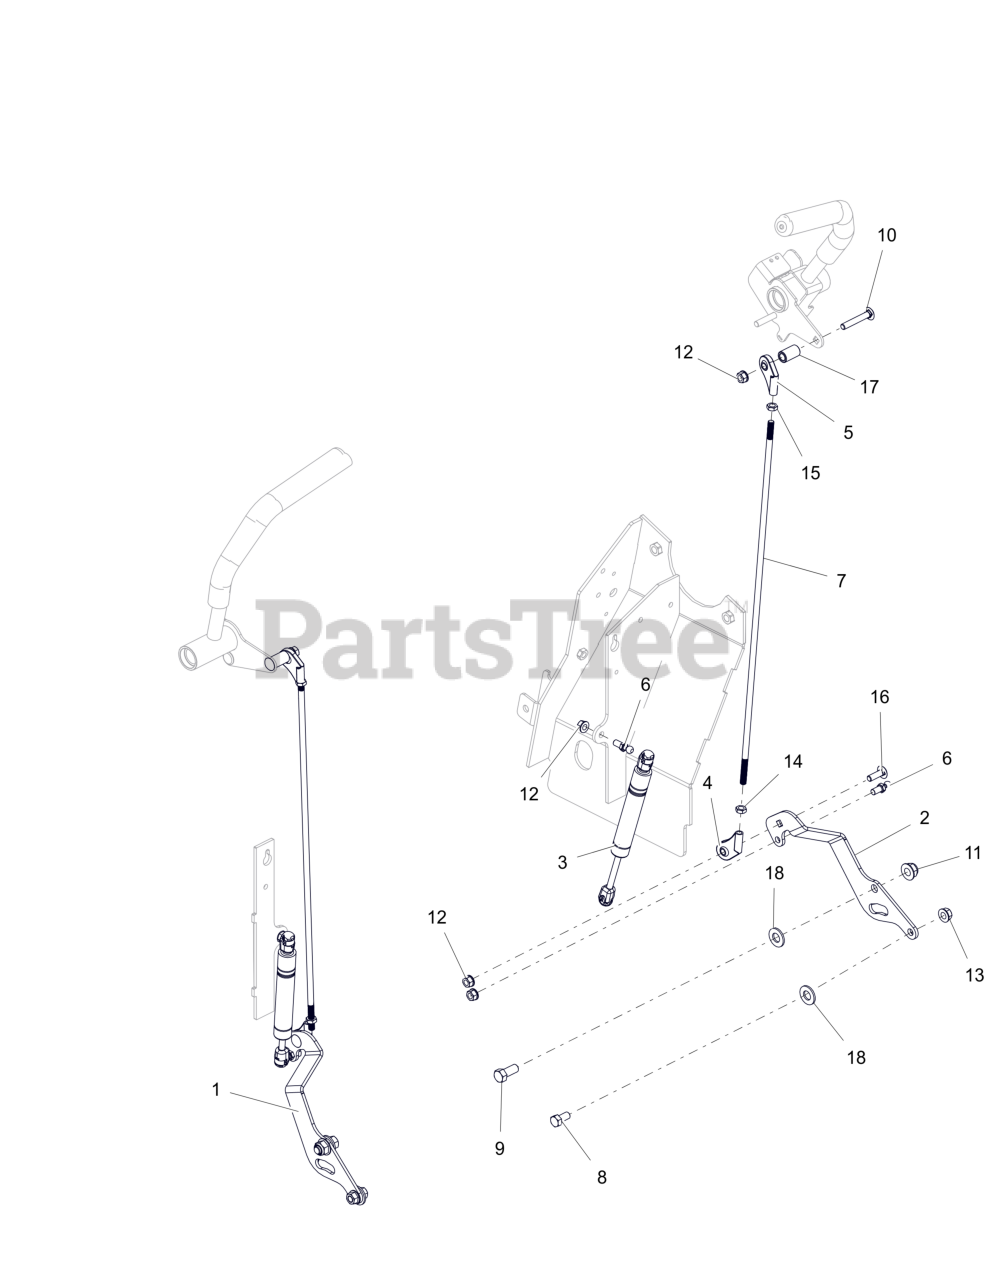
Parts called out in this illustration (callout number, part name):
1	ARM, RH 32-36" DRIVE CONTROL (BLACK)
2	ARM, LH 32-36" DRIVE CONTROL (BLACK)
3	DAMPER, CONTROL
4	END, ROD 5/16-24 RH
5	END, ROD 5/16-24 LH
6	STUD- BALL
7	ROD, STEERING
8	BLT,HEX .38-16X.75 G5 ZCC
9	BLT, HEX 0.4375-14X1 GR5 ZCC
10	BLT, RHSSN .31-18X2.00 G5 ZCC
11	NUT,NYL-FLG .44-14 GF ZCC
12	NUT,LK-CTR-FLG .31-18 GF ZCC
13	NUT-LK-CTR-FLG .375-16 GF ZCC
14	NUT-JAM .312-24 ZCC
15	NUT, JAM-LH .312-24 ZCC
16	BLT,RHSSN .31-18X1.00 G5 ZCC
17	SPACER, .375 X .625 X 1.063 PM
18	WSHR,FLT .531X1.062X.095 ZCC
